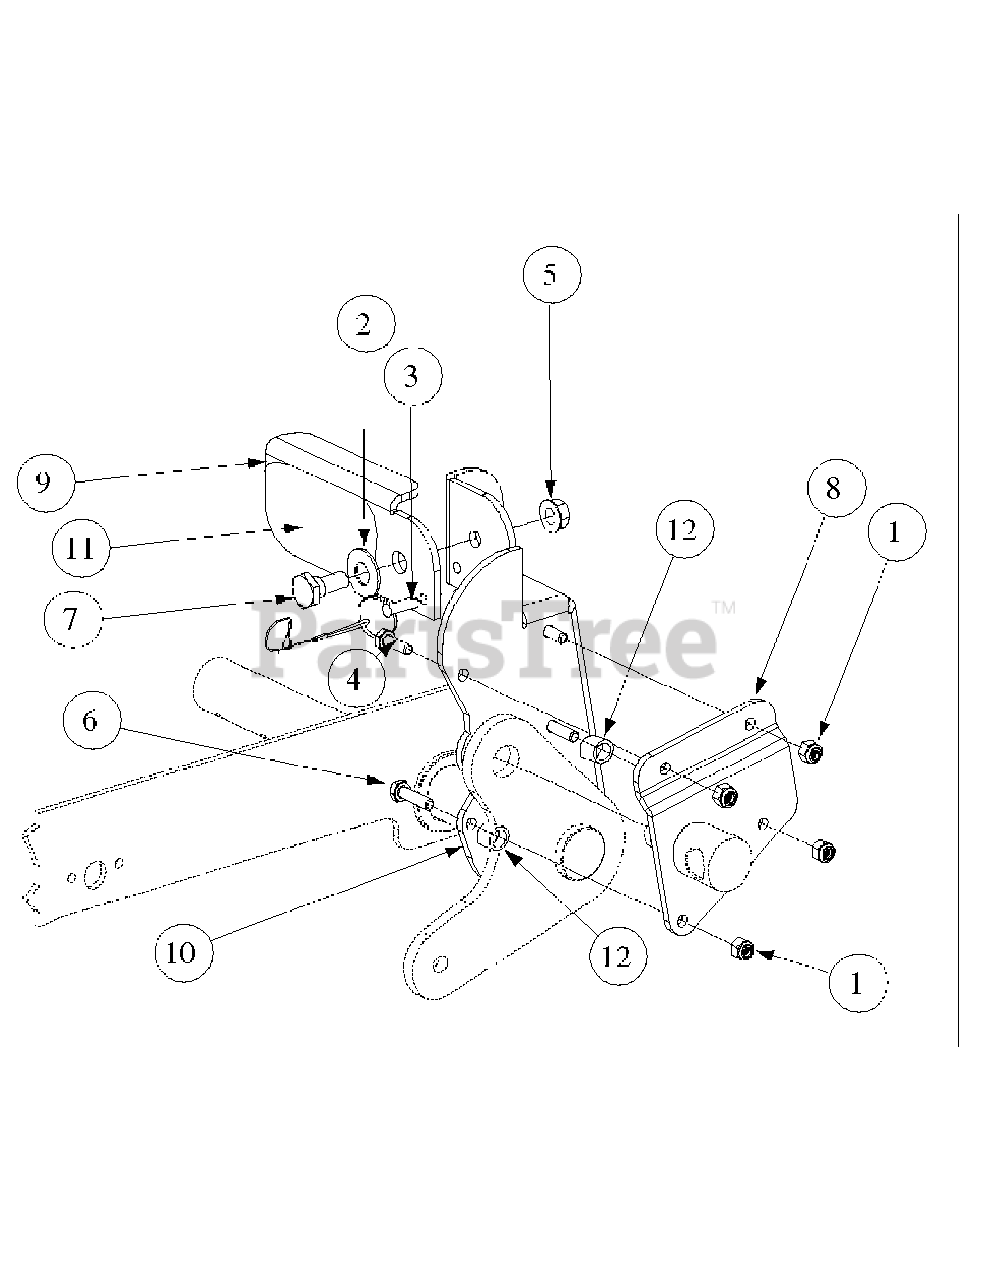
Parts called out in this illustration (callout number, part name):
1	Lock Nut, Nylon Insert, 1/4-20
2	Washer, 1/2 x 1 Shim
3	Detent Pin w/12" Lanyard
4	Hex Cap Screw, 1/4-20, .75
5	Hex Nut, Flange Lock 3/8-16
6	Hex Cap Screw, 1/4-20, 1.00
7	Shoulder Screw, .50 x .27 Lg., 3/8-16
8	Foot Lift Backup Pedal
9	Deck Foot Pedal Lift
10	Deck Foot Pedal Lift
11	Deck Foot Lift Pad
12	Turnbuckle Sleeve
